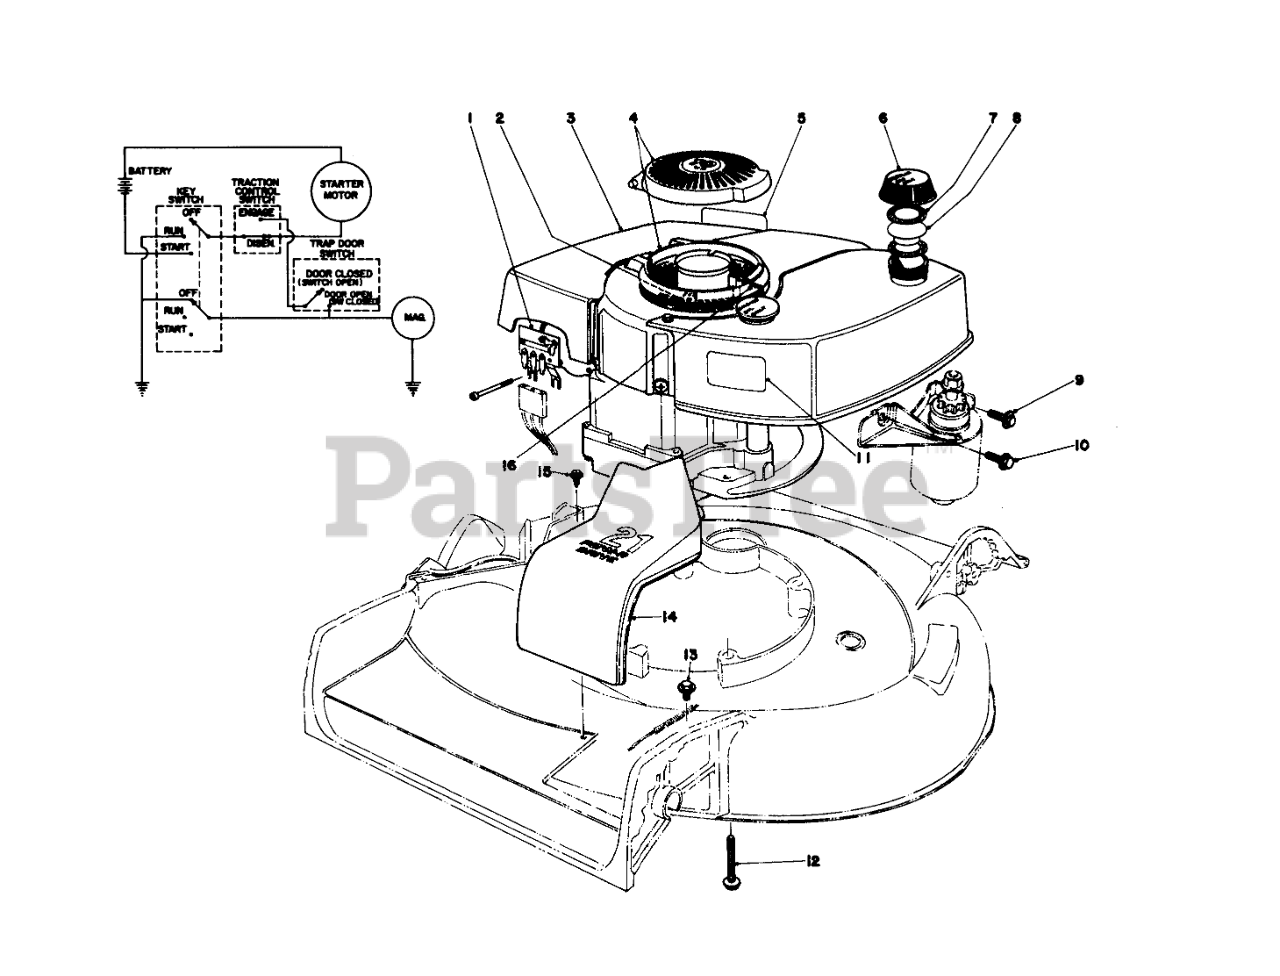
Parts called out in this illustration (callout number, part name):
1	SWITCH & TERM BLK CVR
2	WIRE CLIP
3	Engine
4	Cover
5	Decal Maintenance
6	Gas Cap (Incl. Ref. #7 & 8)
7	GASKET
8	GAS CAP BAFFLE
9	SCREW
10	Screw
11	Decal Engine
12	3/8-16 X 2-3/4 CAPSCR
13	SCREW-HWHTF
14	Cover Belt Drive
15	SCREW
16	SPRING PIN
